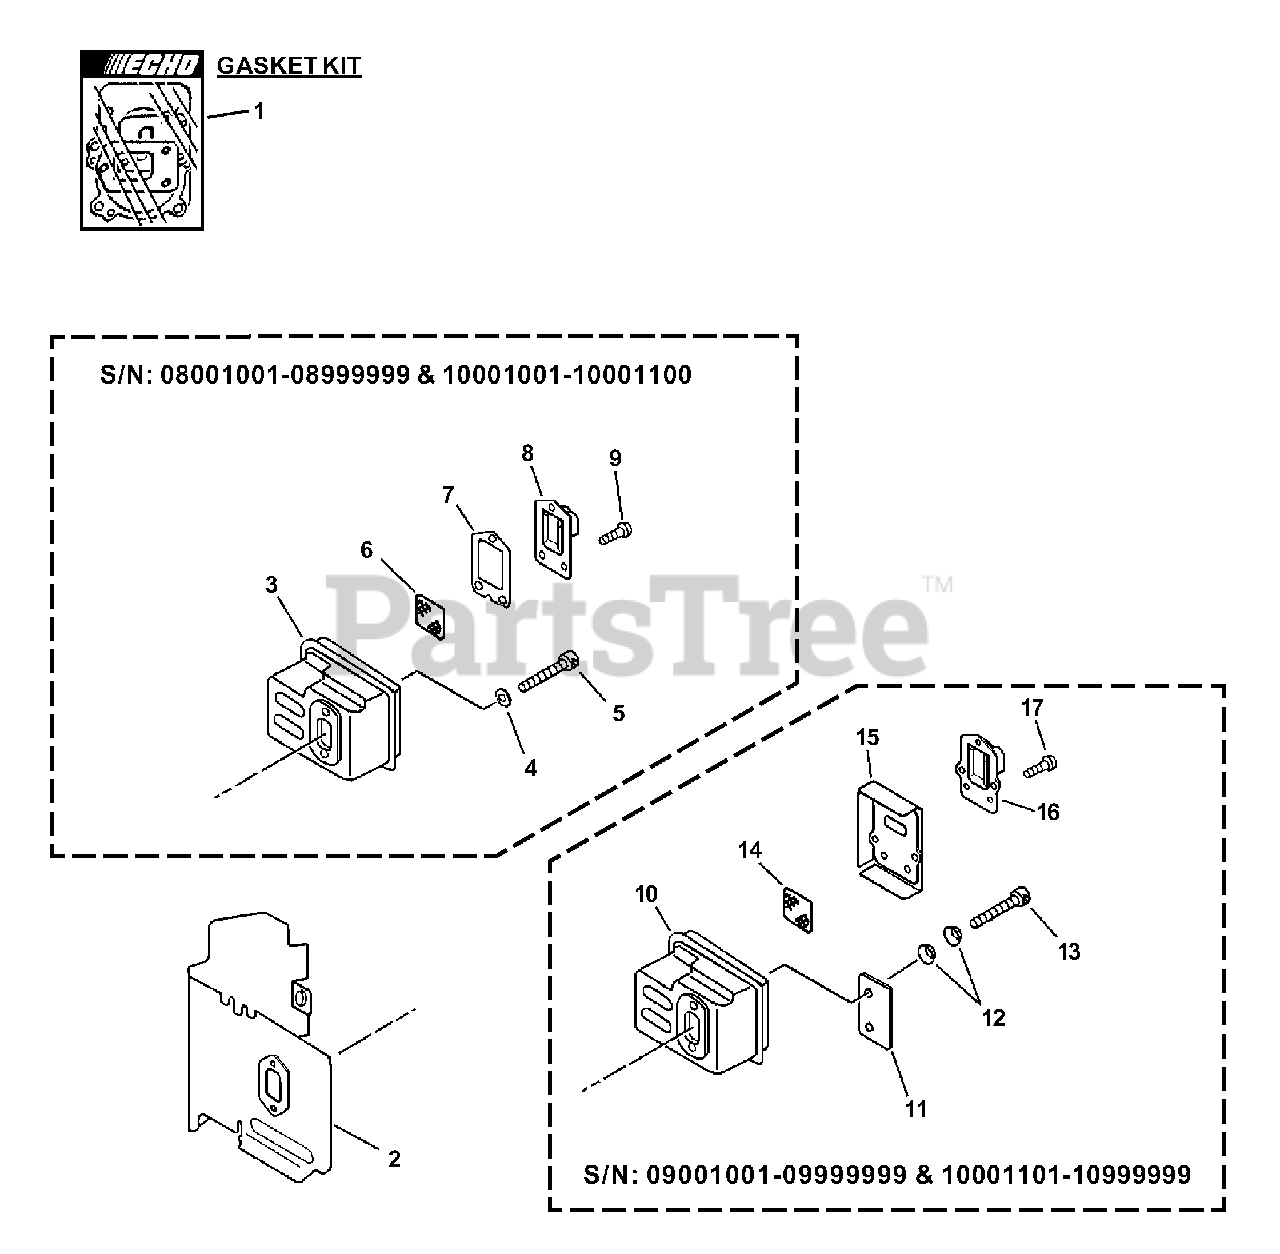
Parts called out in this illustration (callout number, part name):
1	GASKET KIT
2	SHIELD, EXHAUST
3	MUFFLER
4	WASHER, FLAT 5.5×10×0.8
5	BOLT 5×55
6	SCREEN, SPARK ARRESTER
7	GASKET, EXHAUST
8	GUIDE, EXHAUST
9	SCREW 4×10
10	MUFFLER
11	PLATE, EYE
12	CONICAL WASHER
13	BOLT 5×55
14	SCREEN, SPARK ARRESTER
15	GASKET, EXHAUST
16	GUIDE, EXHAUST
17	SCREW 4×12
